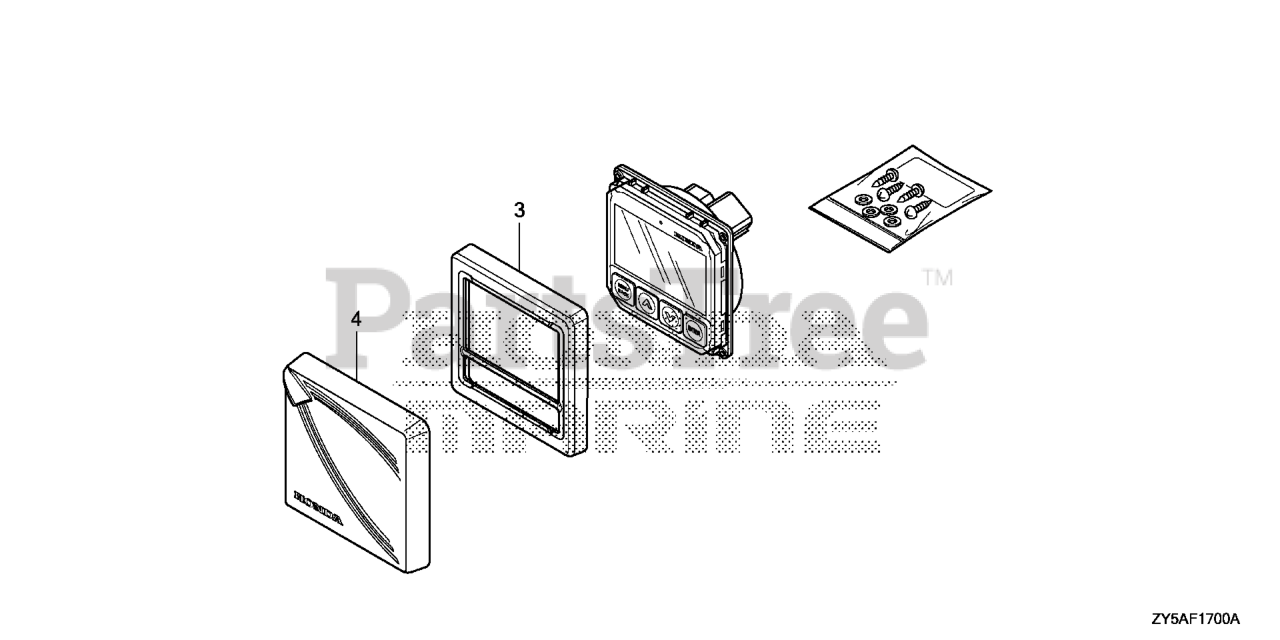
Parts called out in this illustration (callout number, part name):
1	DISPLAY ASSY.
2	DISPLAY UNIT
3	BEZEL, DISPLAY
4	COVER, DISPLAY
